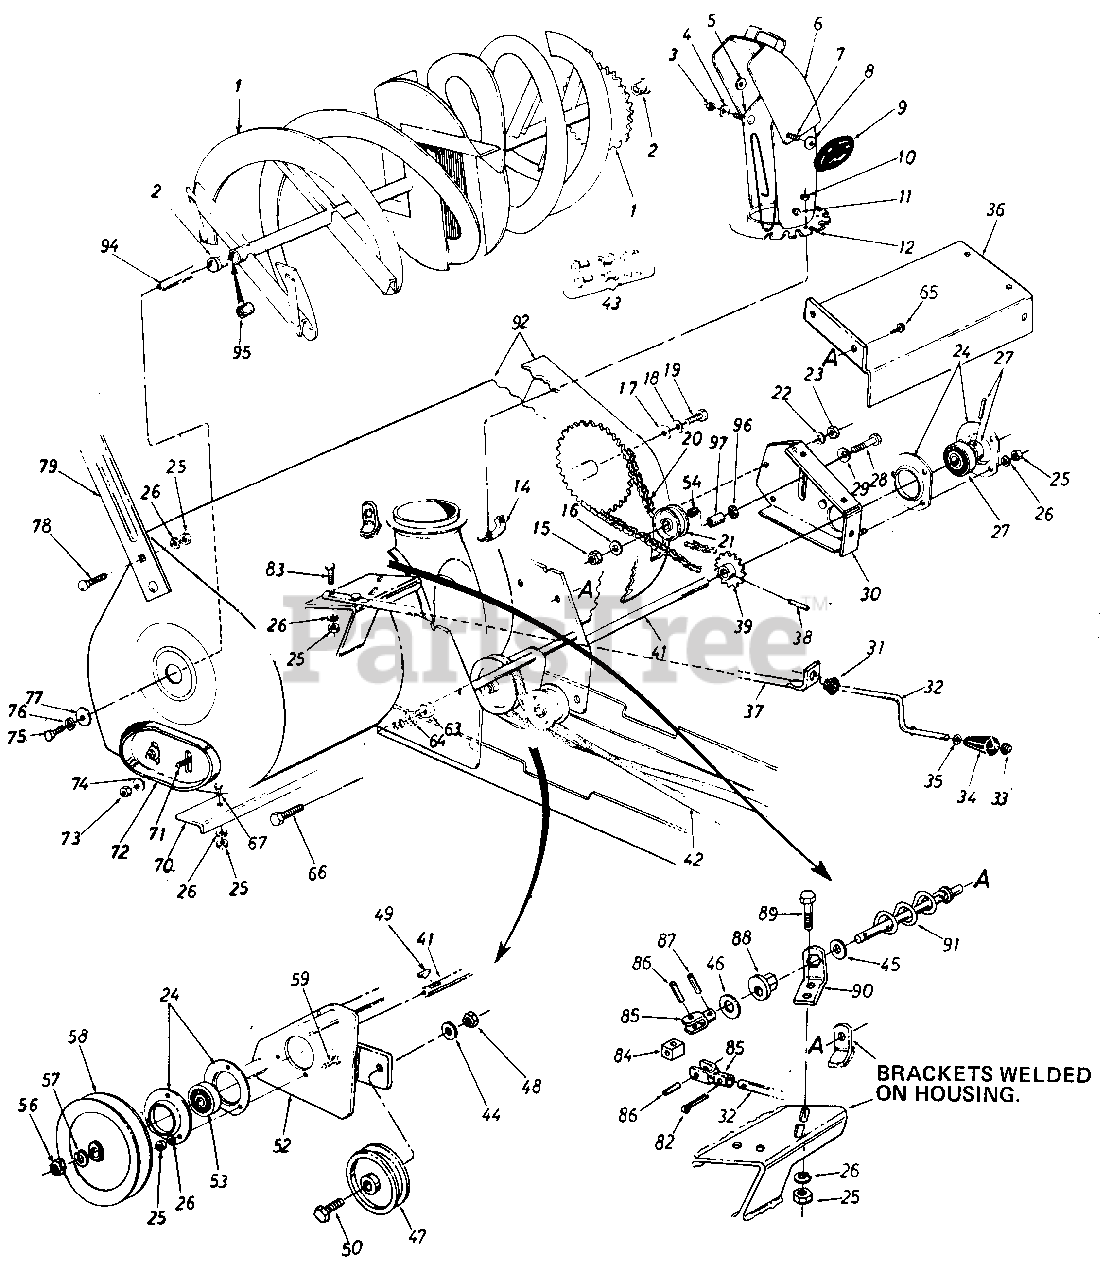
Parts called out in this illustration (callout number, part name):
1	Spiral Ass'y.
2	Flange Bearing
3	Hex Cent. L.-Nut 5/16-18 Thd.
4	Belleville Wash. 3/8" I.D.
5	Flat Washer 3/8" I.D.
6	Top Chute Ass'y.
7	Carriage Bolt 5/16-18 x .62" Lg.*
8	Belleville Wash. 3/8" I.D.
9	Hand Knob
10	Hex Cent. L.-Nut 1/4-20 Thd.
11	PushCap .188" Dia. Rod
12	Chute Ass'y
14	Chute Flang Keeper Ass'y.
15	L.-Nut 3/8 16 Thd.
16	Fl.-Wash.
17	Fl.-Wash.
18	Belleville Wash.
19	Hex Bolt 1/2-13 x 1.00" Lg.*
20	#420 Chain 1/2" Pitch x 77 L in ks
21	Plastic Idler 2.00" O.D.
22	L.-Wash. 1/4" I.D.*
23	Hex Nut 1/4-20 Thd.*
24	Bearing Housing
25	Hex Nut 5/16-18 Thd.*
26	L.-Wash. 5/16" I.D.*
27	Self-Aligning Bearing
28	Hex Bolt 3/8-16 x 1.75" Lg.*
29	Belleville Wash. 3/8" I.D.
30	Chain Guard Ass'y.
31	Grommet
32	Chute Crank .375 Dia. x 39" Lg.
33	Push Nut 3/8" Rod
34	Knob 3/8" Dia. Hole
35	Flat Washer
36	Drive Shaft Cover
39	14 Teeth Sprocket Ass'y.
41	Drive Shaft
42	"V" Belt 1/2" x .88" Lg. (Kevlar)
43	Master Link for #420 Chain
44	L.-Wash. 3/8" I.D.*
45	Fl.-Wash. .385 I.D. x .62" O.D.
46	Fl.-Wash. .390 I.D. x 1.50" O.D.
47	Fl.-Idler with Fldnges
48	Hex Jam L.-Nut 3/8-26 Thd.
49	#61 Hi-Pro Key
50	Hex Bolt 3/8-16 x 1.50" Lg.*
52	Spiral Housing Ass'y.
53	Self-Aligning Bearing
54	Sleeve Bearing .50" I.D.
56	Hex Nut 3/4-10 Thd
57	L-Wash. 3/4" I.D
58	"V"-Pulley .750" I.D. x 6.00" O.D .
59	Hex Sems Bolt 5/16-18 x .75" Lg.*
63	Hex L.-Nutl/2-20 Thd.
64	L.-Wash. 1/2" I.D. x
65	Hex Wash. Hd. Tap Scr. 1/4-20 x .50" Lg.
66	Hex Bolt 1/2-20 x 1.25" Lq*
67	Carriage Bolt 5/16-18 x .62"*
72	Skid Shoe
73	Hex Nut 3/8-16 Thd.*
74	Belleville Wash. 3/8" I.D.
75	Hex Bolt 1/2-13 x 1.00" Lg.*
76	Belleville Wash. 1/2" I.D.
77	Fl.-Wash.
78	Carriage Bolt 5/16-18 x .62" Lg.*
79	Drift Cutter
82	Cotter Pin 3/32" Dia.
83	Hex Bolt 5/16-18 x 1.50" Lg.*
84	Joint Block
85	Joint Bracket Ass'y.
86	Spring Pin Roll 3/16" Dia. x .75" Lg.*
87	Spring Pin Roll 1/8" Dia. x .75" Lg.*
88	Hex Bushing .385 I.D.
89	Carriage Bolt 5/16-18 x .62
90	Chute Crank Bracket
91	Chute Crank Ass'y.
92	Spiral Housing Ass'y.
94	Spiral Axle Ass'y.
95	Sleeve Bearing
96	Flat Washer
97	Idler Spacer
